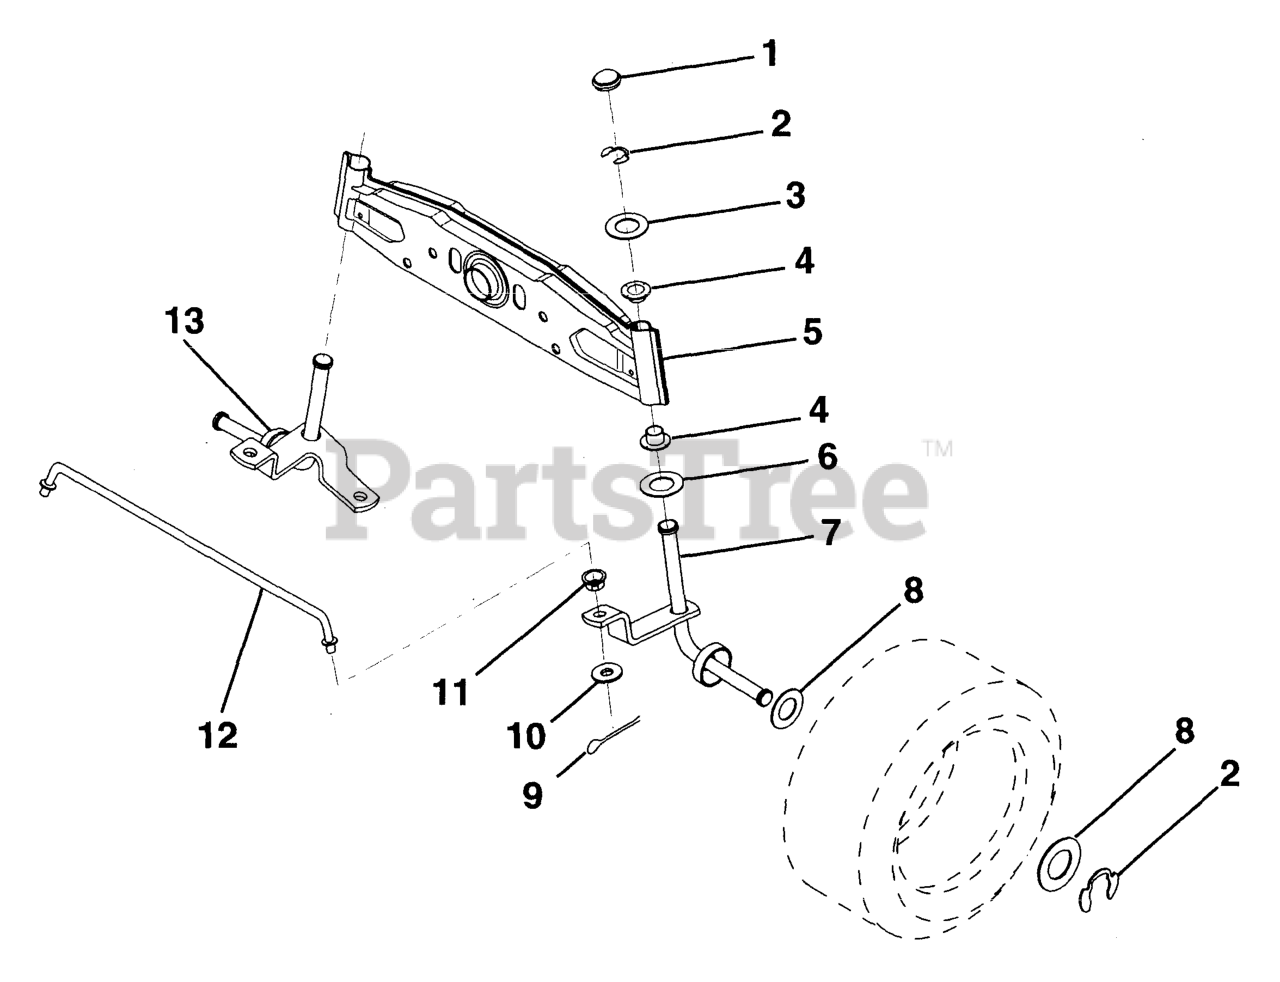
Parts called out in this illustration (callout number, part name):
1	CAP.SPINDLE.BLACK
2	CAP.SPINDLE.BLACK
5	AXLE FRONT
6	THRUST WASHER
7	SPINDLE RH
9	COTTER PIN
10	WASHER
11	BUSHING.DRAGLINK (2 2)
13	SPINDLE LH
